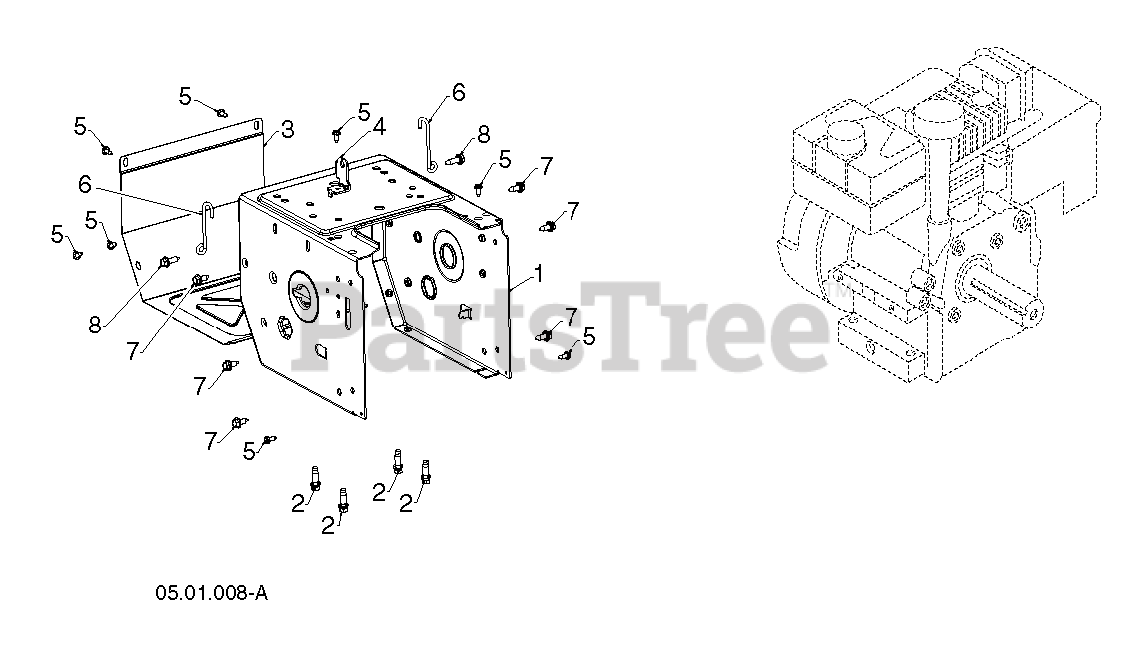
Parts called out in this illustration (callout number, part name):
1	FRAME MS 668
2	BOLT 3/8-16X1-1/8
3	COVER COVER.FRAME MS668 ORANGE
4	BRACKET.SHIFTER.BZP
5	SCREW.HEX HEAD W/COLLAR 1/4-20
6	WIREFORM.SUPPORT.CABLE
7	BOLT.HEX.HD.WASHER.5/16-18X.75
8	SCREW HEXAGON HEAD WITH COLLAR
